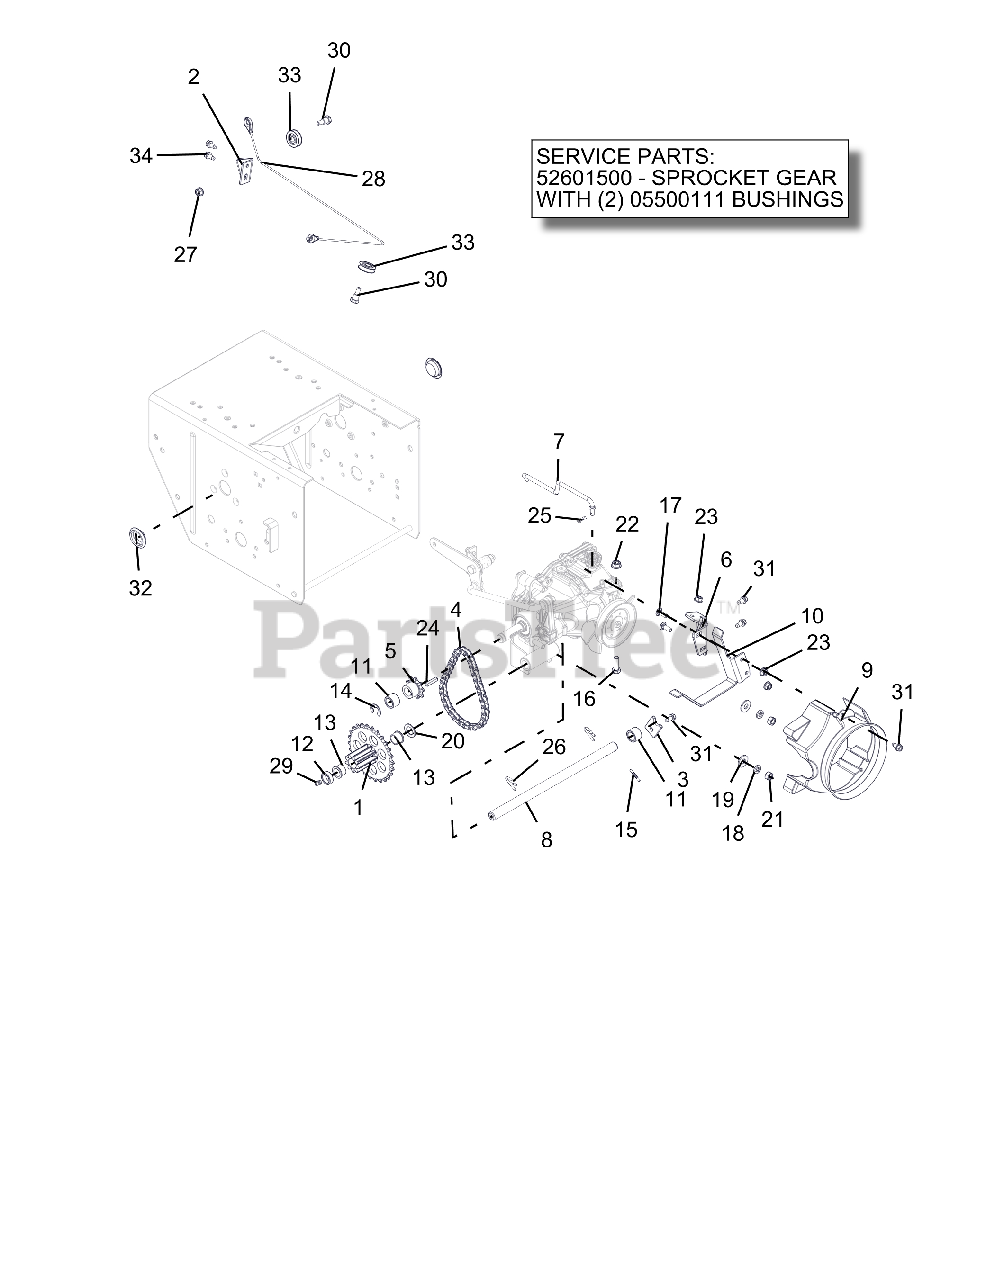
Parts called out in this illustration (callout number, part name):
1	PINION, SPROCKET
2	BRKT, CABLE PULLEY
3	TAB, ANTI - ROTATION
4	CHAIN, ROLLER - #41 w/32 PITCHES
5	SPROCKET, PINION 9T, W/KEY
6	BRKT, CLUTCH CABLE
7	ROD, HYDRO DUMP
8	SHAFT, PINION
9	SHROUD, HYDROGEAR RT-310
10	FINGER, BELT - FLAT
11	SPCR, .635 X .880 X .611
12	BSHG, SLV , .635X.880X.305
13	BSHG, FLG .625 X .750 X .500 X .875
14	RING, RETAINING-E .625X.042
15	PIN-GRV .125X1.00 TP E
16	BLT-HEX .31-18X1.00 GR5 YWZC
17	BLT-RDHDSQNK .25-20X.75 G5 YWZC
18	WSHR-LK .31X.097 HVY YWZC
19	WSHR-FL-STL.38X.875X.083 YWZC
20	WSHR-FL-STL .630X1.005X.062 YWZC
21	NUT-HEX .31-18 YWZC
22	NUT, LK-TOP-FLG .312-18 YWZC
23	NUT, LK-TOP-FLG .25-20 YWZC
24	KEY-SQ .188X.188X1.00
25	PIN-HAIR INT .06X.18X.77
26	PIN, SPRING CLIP
27	NUT, LK-TOP-FLG .25-20 YWZC
28	CABLE, TRACTION , HYDRO PRO
29	ZERK, FITTING .25X.125 DRIVE IN
30	BOLT, SHLDR -.375 X .375 X .25-20
31	SCR-TAP .25-20X.50 HWH TR YWZ
32	PLUG, HOLE - 1.125"
33	PULLEY, CABLE
34	SCR-TAP .25-20X.50 HWH TR YWZ
35	SPROCKET GEAR
35	BUSHING
